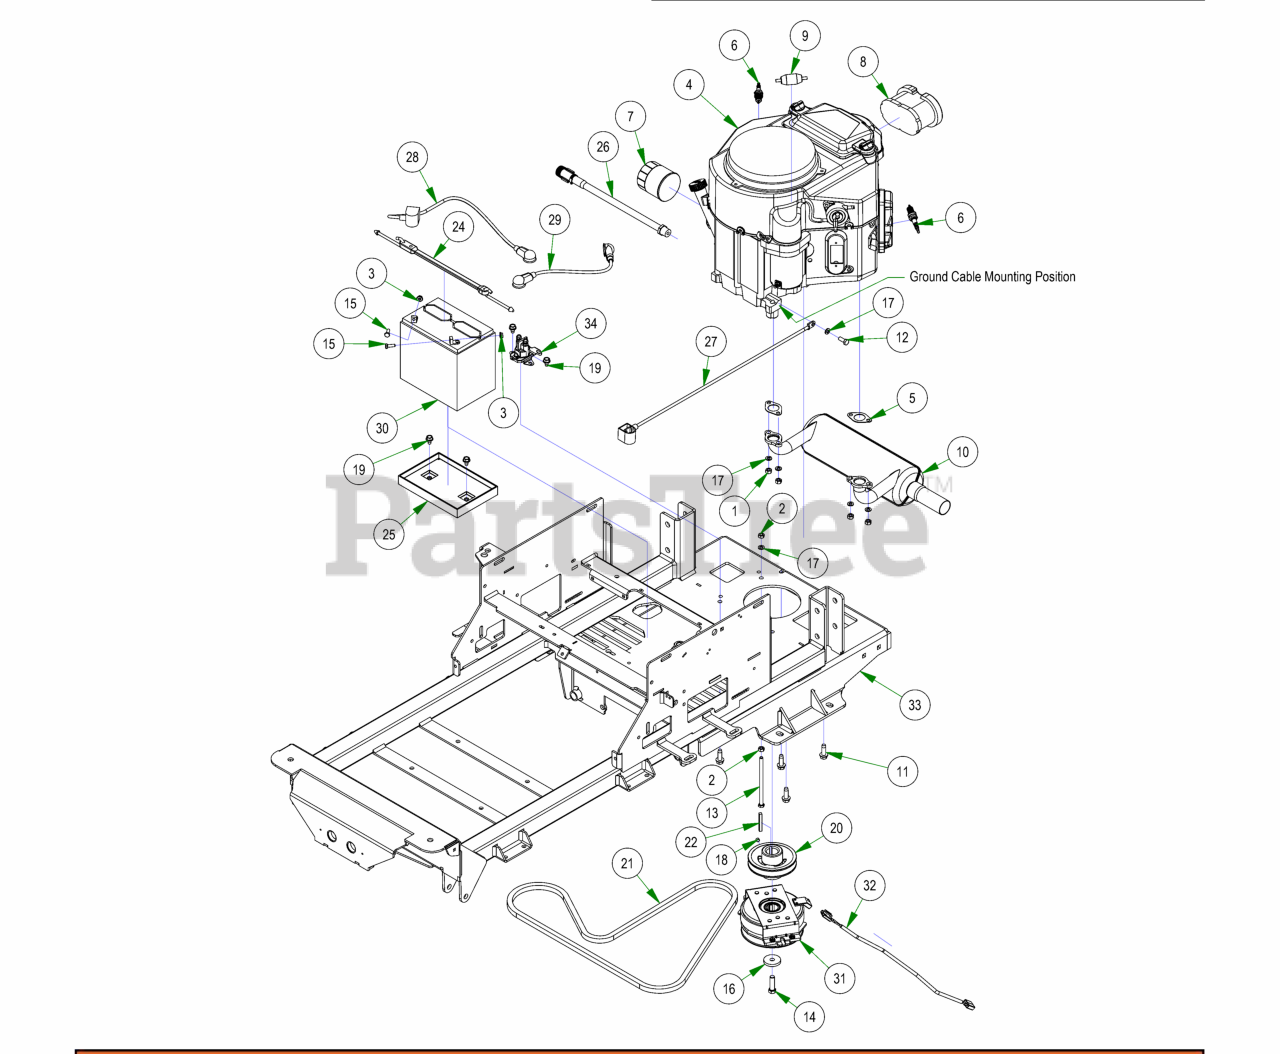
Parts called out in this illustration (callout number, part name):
1	M8-1.25 DIN 934 HEX NUT (CL.8) ZINC
2	5/16-18 HEX NUT ZINC
3	1/4-20 HEX SERRATED FLANGE NUT HARD/ZINC
4	FS730V Engine
5	Exhaust Gasket
6	Spark Plug - Kawasaki
7	22-26 Kaw Oil Filter FR Engine
8	Kawasaki Air Filter
9	Universal Inline Fuel Filter
10	Kawasaki Muffler 1251
11	3/8-16 X 1-1/8 HEX WASHER UNSLOT SERRATED (TRI-LOB) TRS ZINC YELLOW
12	M8-1.25 X 20MM DIN 933 HEX TAP BOLT (CL 8.8) ZINC
13	5/16-18 X 5-1/2 HEX CAP SCREW (GR.5) ZINC
14	7/16-20 X 1-1/2 HEX CAP SCREW (GR.8) w/ Patch
15	1/4-20 X 3/4 HEX CAP SCREW (GR.5) ZINC
16	CLUTCH WASHER
17	5/16 SPLIT LOCKWASHER ZINC
18	5/16-24 X 1/4 SOCKET SET SCREW (CUP PT) PLAIN
19	5/16-18 X 1/2 HWH unslot (F) tcs zinc
20	4 3/4 Motor Pulley
21	75.8" Pump Belt
22	1/4 X 2 SQ MACHINERY KEY 1018 STL PLAIN
23	2023 Battery Hold Down Assembly
24	2023 Rubber Battery Hold Down Strap
25	Battery Tray
26	Kawasaki Oil Drain
27	24 inch Black Cable – MZ/ZT
28	24" Red Battery Cable
29	12" Red Battery Cable
30	SP-35 Battery
32	Clutch Pigtail
33	2023 Maverick Frame - Painted
